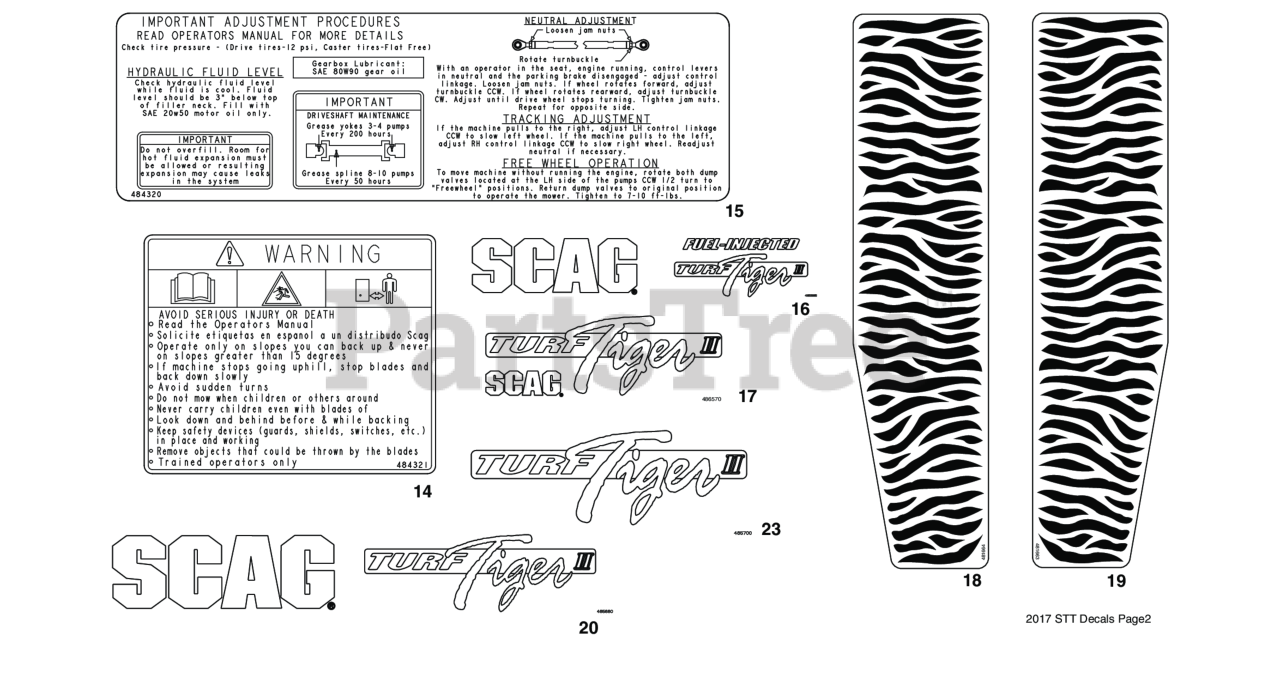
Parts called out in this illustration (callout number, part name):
14	Decal, Start/Drive Procedure
15	Decal, Checks and Adjustments
16	Decal, Hood - STTII Fuel Injected
17	Decal, Turf Tiger II
18	Decal, Stripes-RH
19	Decal, Stripes-LH
20	Decal, Hood - STTII
23	Decal, Turf Tiger II
